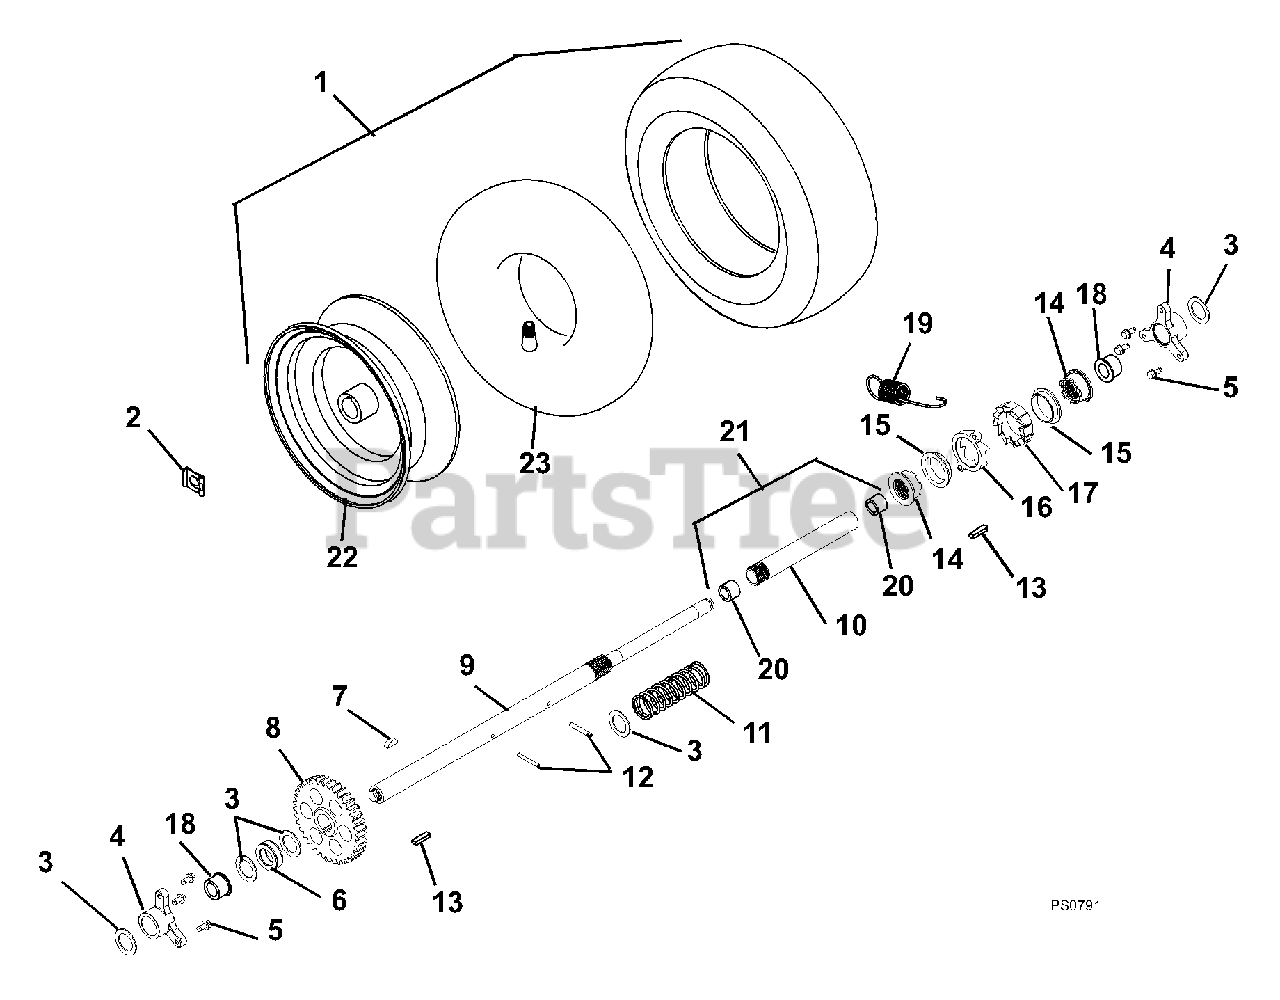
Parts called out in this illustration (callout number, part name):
1	TIRE/WHEEL,RH 15X5.00-6 REMOTE
2	CLIP, SNAP .625 DIA
3	WSHR-FL-STL 1.010X1.505X.062YZ
4	BUSHING, RAKE SHAFT 1"
5	@SCR-TAP .25-20X.50 HWH TR YWZ
6	SPACER 1.005X1.5075X.375
7	KEY-WDRF .25X.750X.313 SAE91
8	GEAR, SPUR
9	AXLE, DIFFERENTIAL-LONG
10	AXLE, DIFFERENTIAL-SHORT
11	SPRING, COMPRESSION
12	PIN-ROLL .188X1.50
13	KEY-RECT .25X.188X1.00
14	CLUTCH, DOG - SLIDING
15	BUSHING, FLANGE
16	GEAR, CLUTCH
17	GEAR, RATCHET
18	BSHG-FLG SPLIT NYLINER 1.0" HP
19	SG-TENS .06X.62X2.94
20	BSHG-SLV .706X.764X.75 BRZ
21	AXLE, DIFFERENTIAL-W/BUSHINGS
22	HUB, WHEEL - 15X5-6 REMOTE
23	TUBE 15 X 5.00-6
